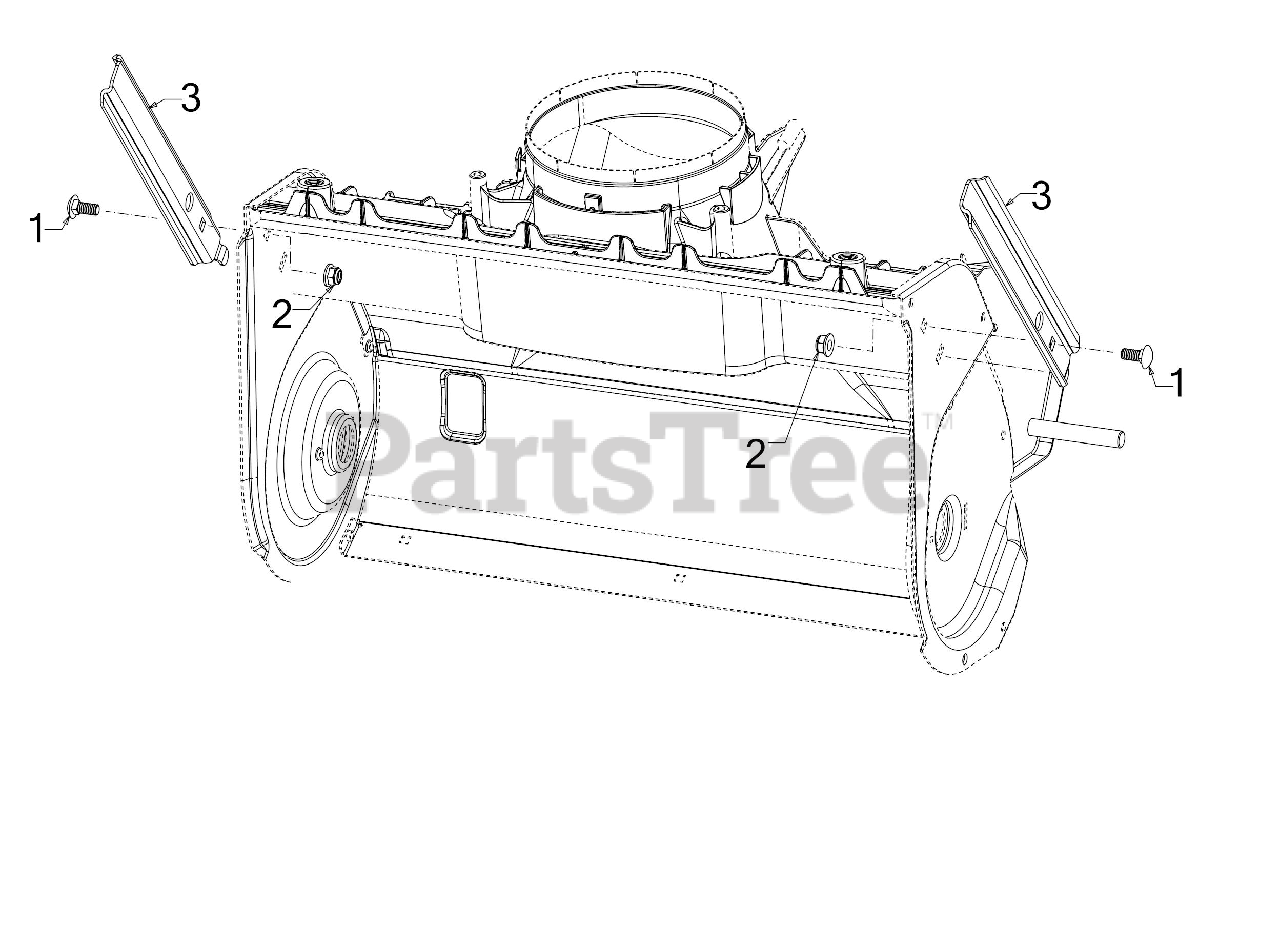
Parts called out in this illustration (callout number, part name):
1	CARRIAGE BOLT 5/16-18 x .75
2	FLANGE LOCK NUT 5/16-18
3	DRIFT CUTTER BLADE
